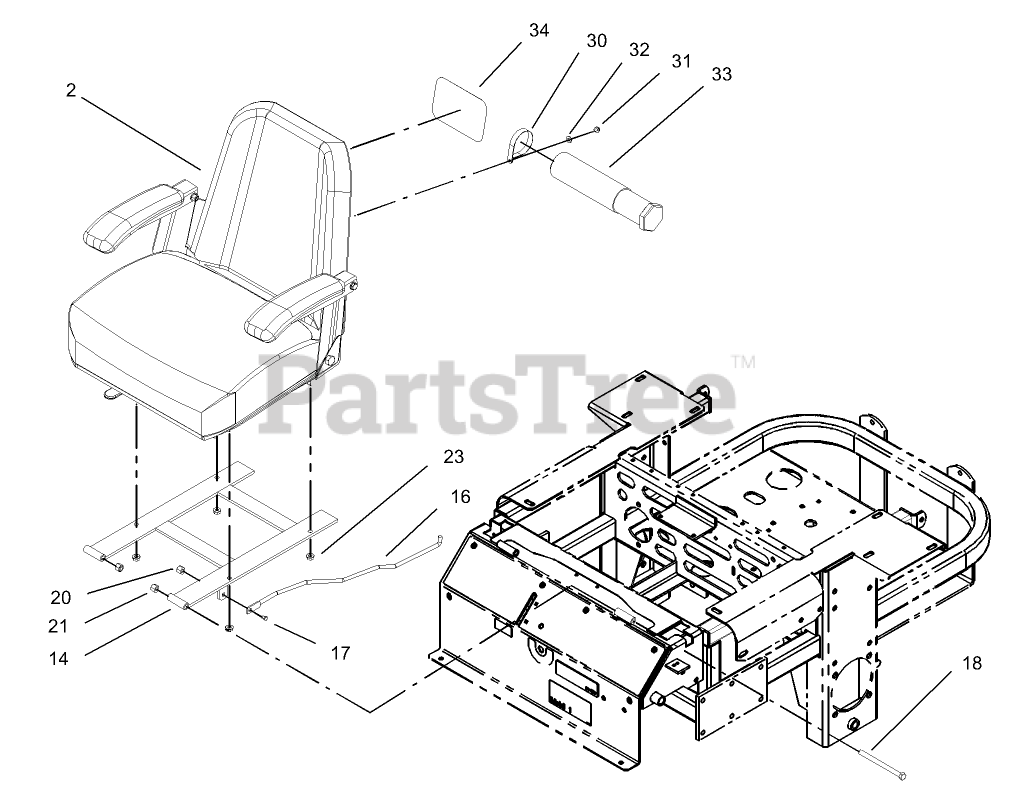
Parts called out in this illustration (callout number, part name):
2	SEAT ASM
14	FRAME-SEAT
16	ROD-HOLDUP, SEAT
17	SCREW-HH
18	SCREW-HH
20	NUT-LOCK, NI
21	NUT-LOCK, NI
23	NUT-HF
30	CLAMP-R
31	SCREW-HWHTF
32	WASHER-FLAT
33	TUBE-MANUAL
34	DECAL
